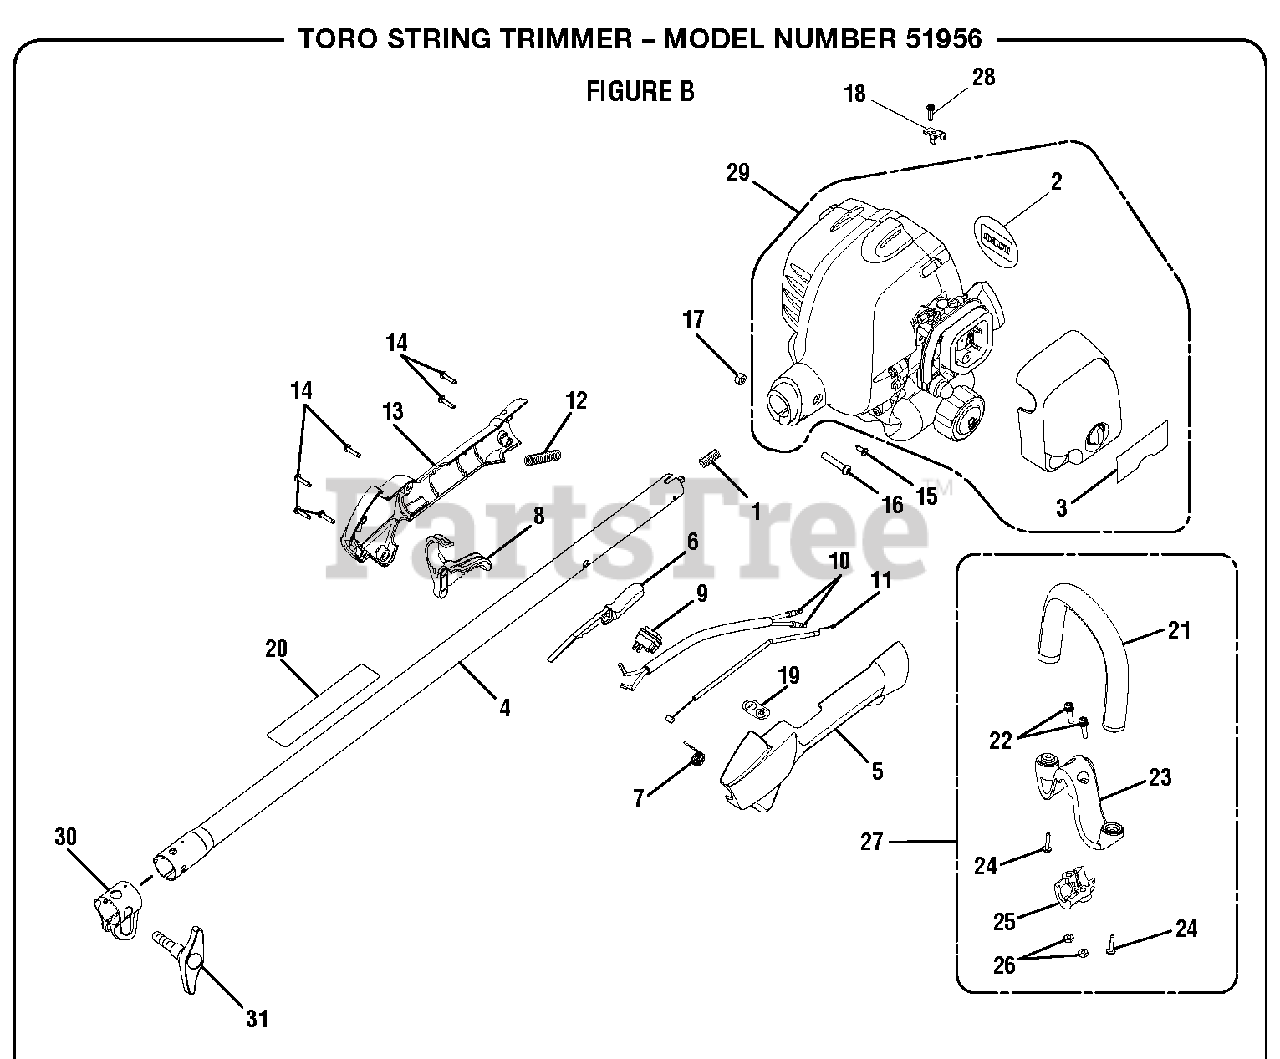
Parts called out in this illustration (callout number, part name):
1	Compression Spring
2	Logo Plate
3	Lower Start Label
4	Upper Shaft Assembly
5	Rear Handle Support
6	Lock-off Button
7	Trigger Spring
8	Trigger
9	On/Stop Switch
11	Cable, Throttle
12	Corrugated Tube
13	Rear Handle Cover
14	Screw (M4 x 16 mm)
15	Screw (#8-16 x 1/2 in Tri-Lobular)
16	Screw (M6 x 1-30 mm)
17	Hex Nut (M63 x 1)
18	Throttle Cable Clamp
19	On/Stop Label
20	Warning Label
21	Front Handle w/Grip
22	Screw (#12-24 x 1 in, Slotted Torx)
24	Screw (10-14 x 1 in)
25	Clamp
26	Hex Nut (12-24)
27	Front Handle Assembly
28	Screw (M4 x 16 mm)
29	Powerhead Assembly
30	Boom Clamp
